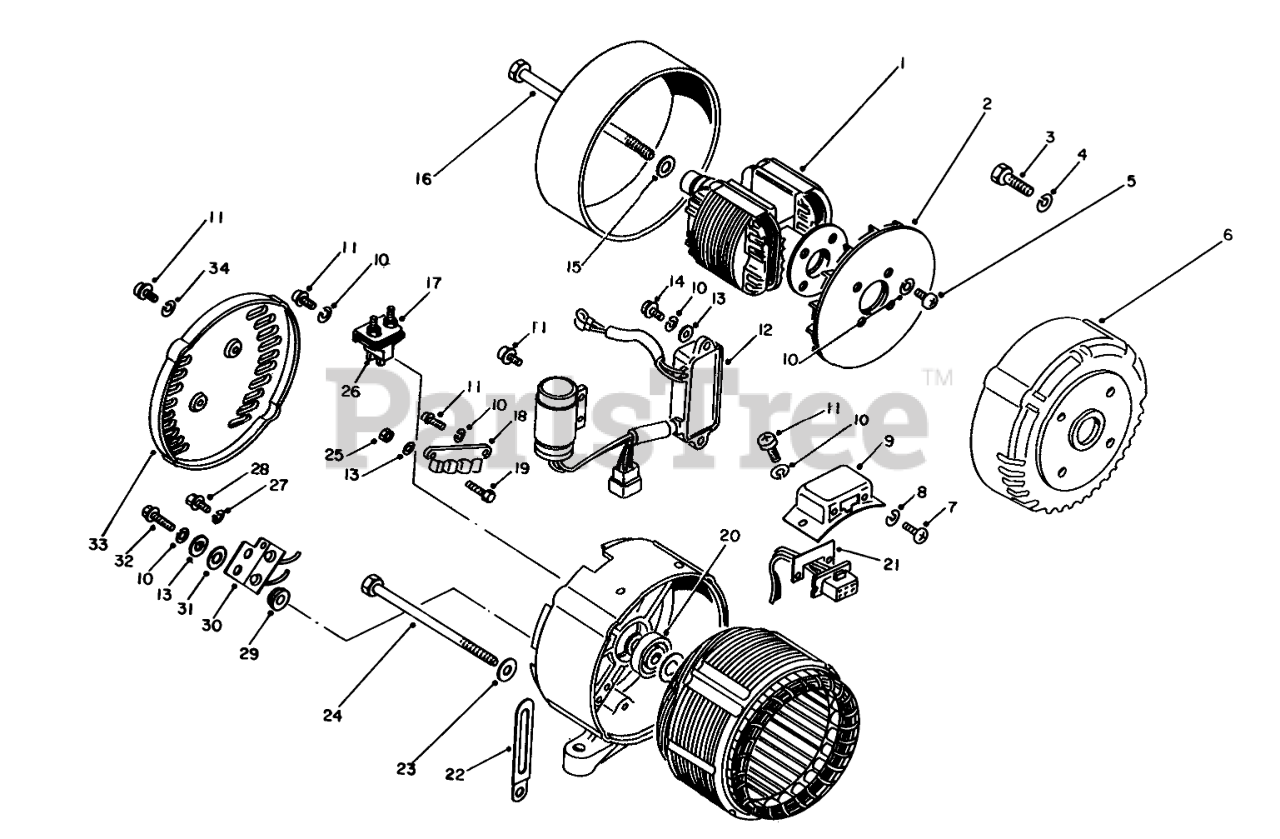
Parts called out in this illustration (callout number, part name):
1	Rotor
4	Lockwasher
5	Screw
6	Generator Assembly (Incl. Ref. #1, 2, 4, 10, 15, 16, & 20)
7	SCREW
8	Lockwasher
9	COUPLER COVER
10	Washer
11	SCREW
12	REGULATOR
13	WASHER
14	Screw
15	Washer
17	Holder
18	Terminal
20	Bearing
21	Plate
22	Clamp
23	Washer
26	BRUSH
27	Lockwasher
29	Brush
30	DIODE
31	Washer
32	Screw
34	Washer
